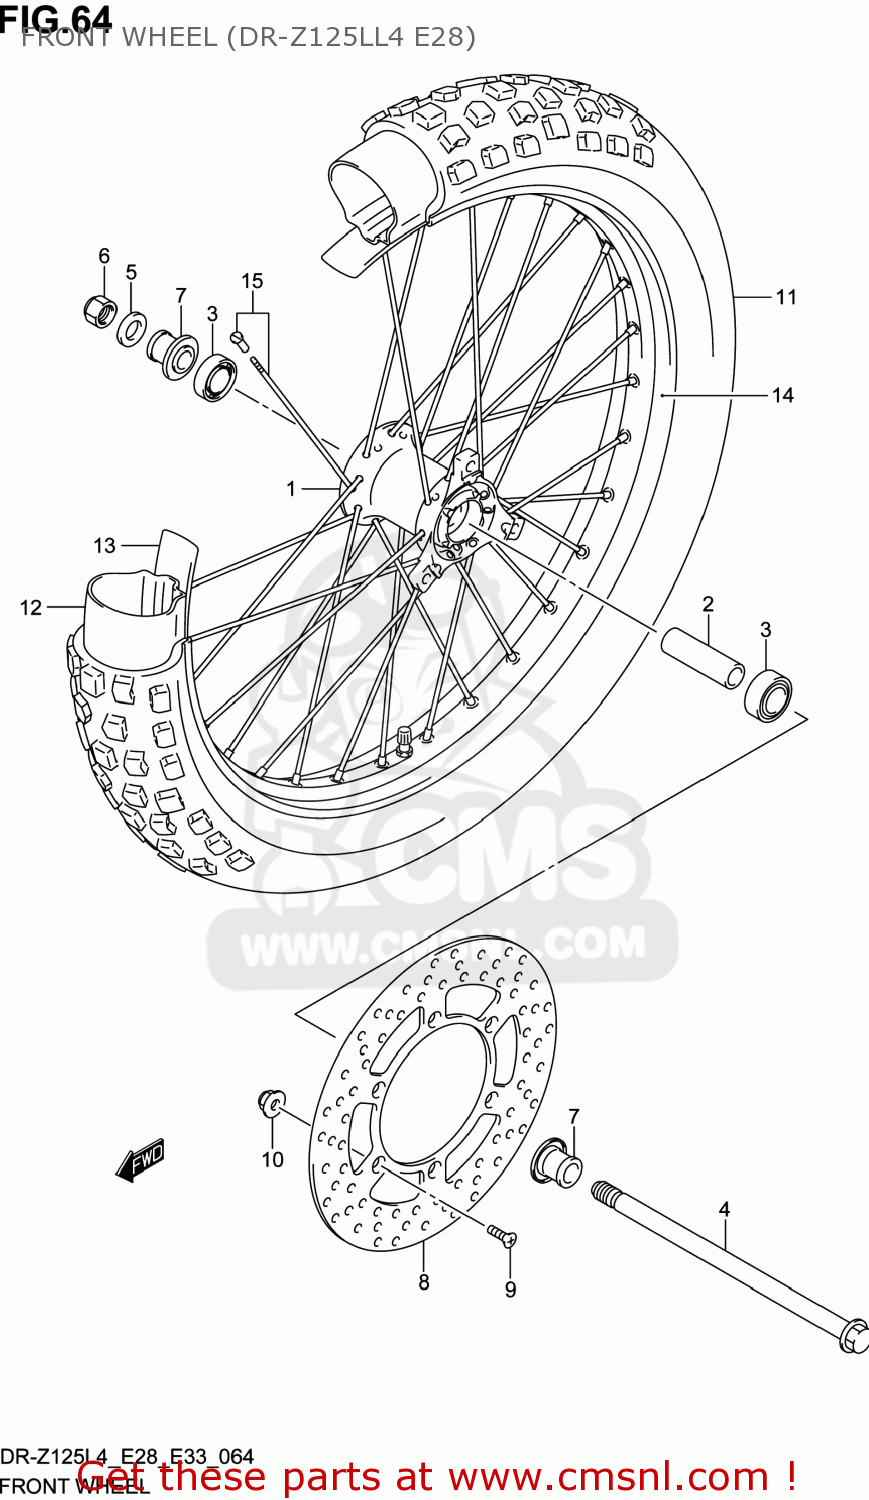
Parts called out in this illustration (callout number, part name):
1	HUB,FR WHEEL
2	SPACER,FR HUB BEARING
3	BEARING (12X32X10)
4	AXLE,FR
5	WASHER(12.5X24X3.2)
6	NUT
7	SPACER,FR AXLE
8	DISC,FR BRAKE
9	SCREW(6X22)
10	NUT
11	TIRE,FR
12	TUBE ASSY,WHEEL INNER
13	PROTECTOR,WHEEL INNER TUBE
14	RIM,FR WHEEL(19X1.40)
15	SPOKE SET,FR WHEEL
